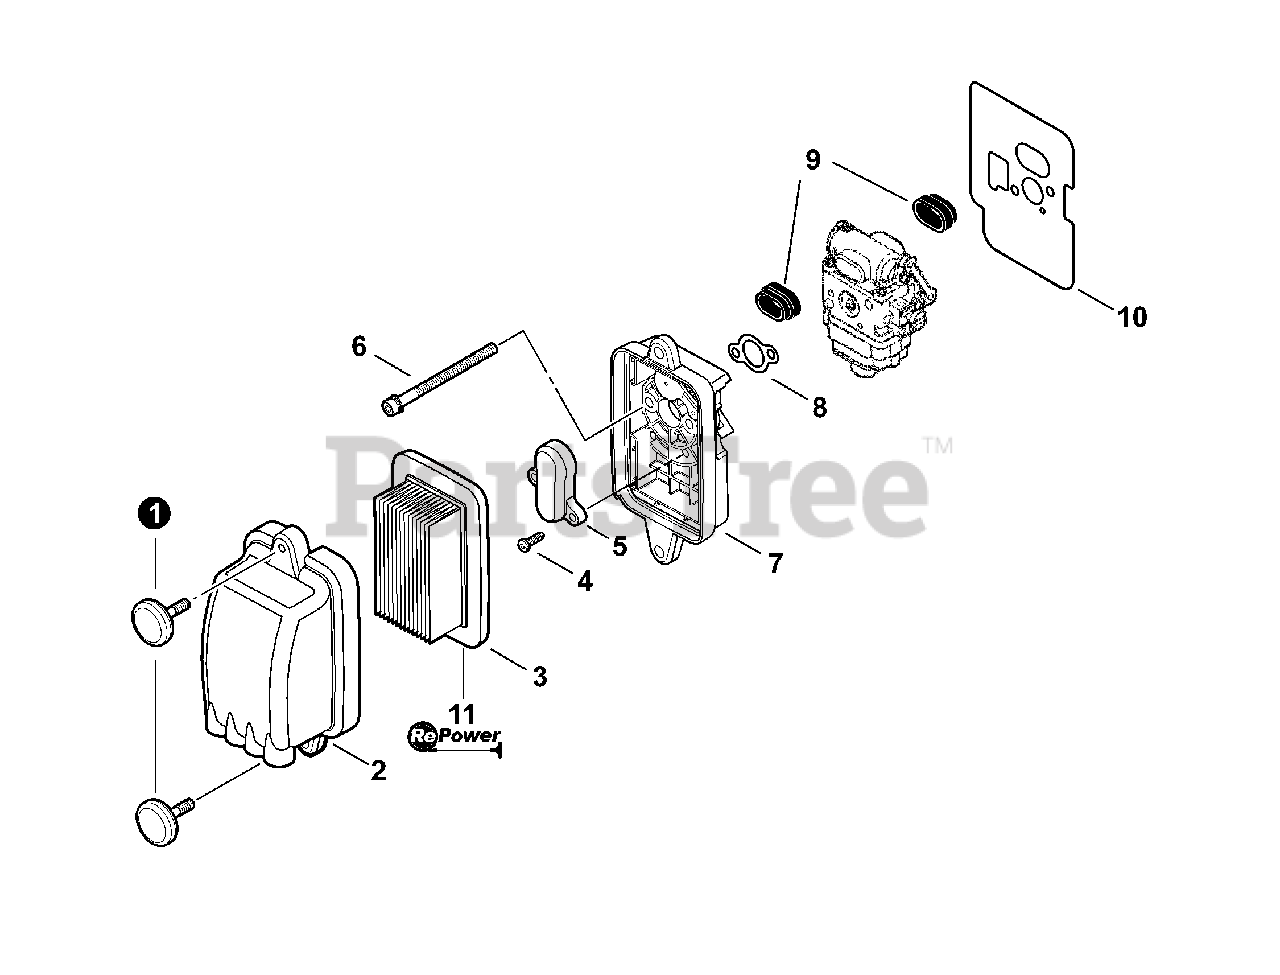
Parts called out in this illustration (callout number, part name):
1	THUMBSCREW
2	COVER, AIR FILTER
3	FILTER, AIR
4	SCREW - 4×14
5	COVER, PREVENT
6	SCREW - 5×65
7	CASE, AIR FILTER
8	GASKET, INTAKE
9	CONNECTOR
10	SHIELD, INTAKE
11	RePower TUNE-UP KIT
